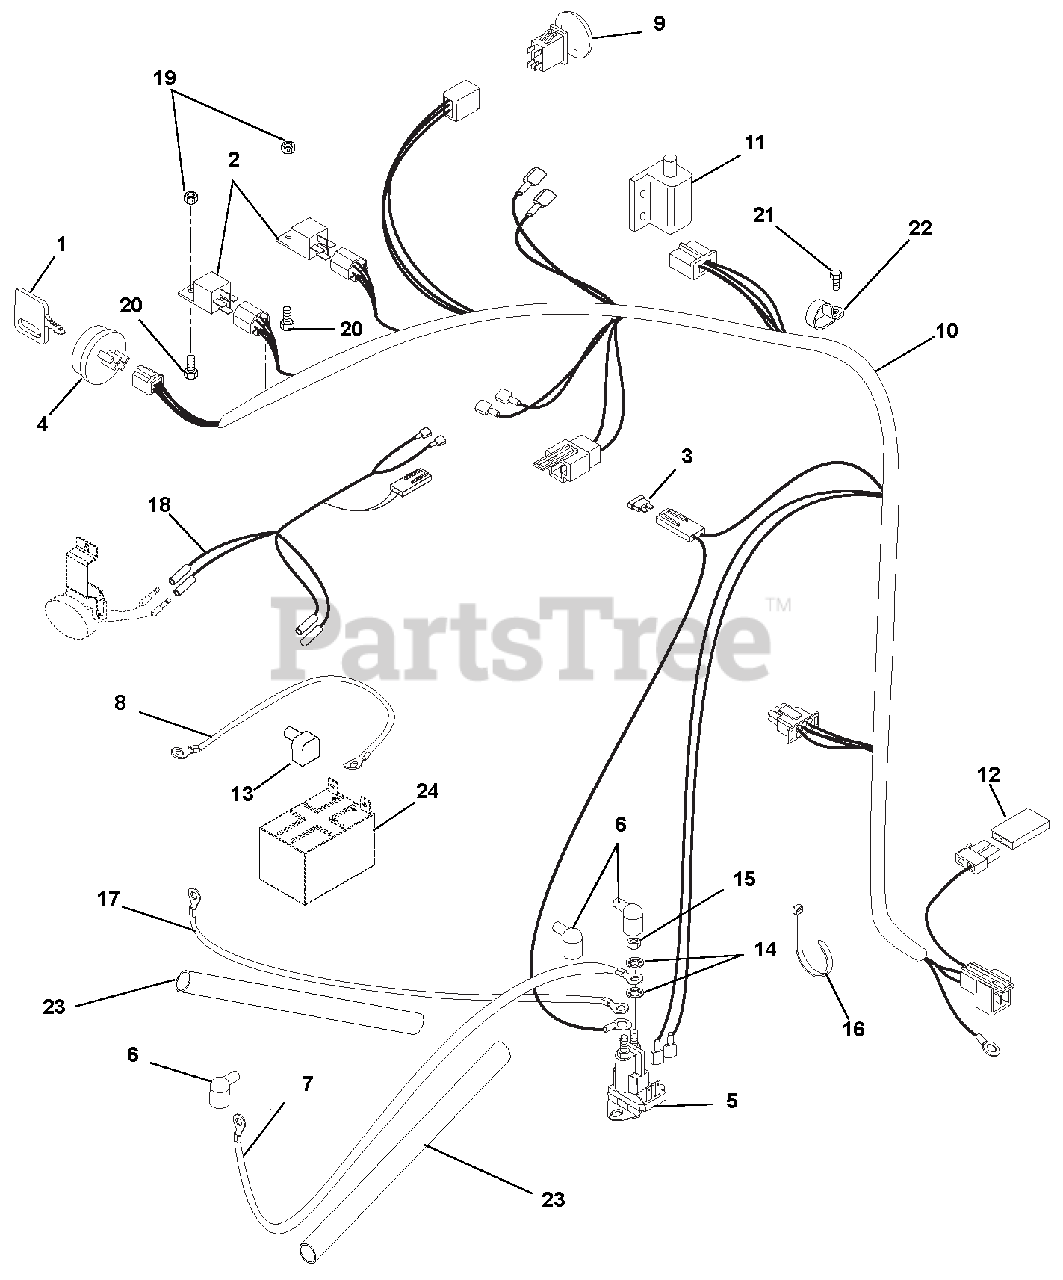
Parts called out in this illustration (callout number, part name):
1	KEY -W/CAP
2	RELAY
3	FUSE-25 AMP ATC TYPE
4	KEY SWITCH
5	SOLENOID, HP RTV
6	BOOT, EYELET TERMINAL
7	STARTER CABLE
8	CABLE-GROUND .25 X 13.00 X .31
9	SWITCH, CLUTCH
10	HARNESS, ZTXL/ZOOMXL
11	SWITCH- DOUBLE POLE N.O./N.O.
12	DIODE, CONNECTOR SHELL
13	INSULATOR
14	WSHR-LOCK INT .31 YWZC
15	NUT-JAM .31-24 YWZC
16	CABLE TIE LG 5-1/2
17	POSITIVE CABLE
18	HARNESS, XL HEADLIGHT
19	@NUT-LK-NYL 10-24 W/INSRT YWZC
20	@SCR-MCH 10-24X.75 HWH YWZC
21	@SCR-TAP .38-16X.50 HWH TR YWZ
22	CLAMP, CUSHIONED STEEL .75
23	SLEEVE, ANTI-ABRASION
24	BATTERY, 12V; 215 CCA GEP
